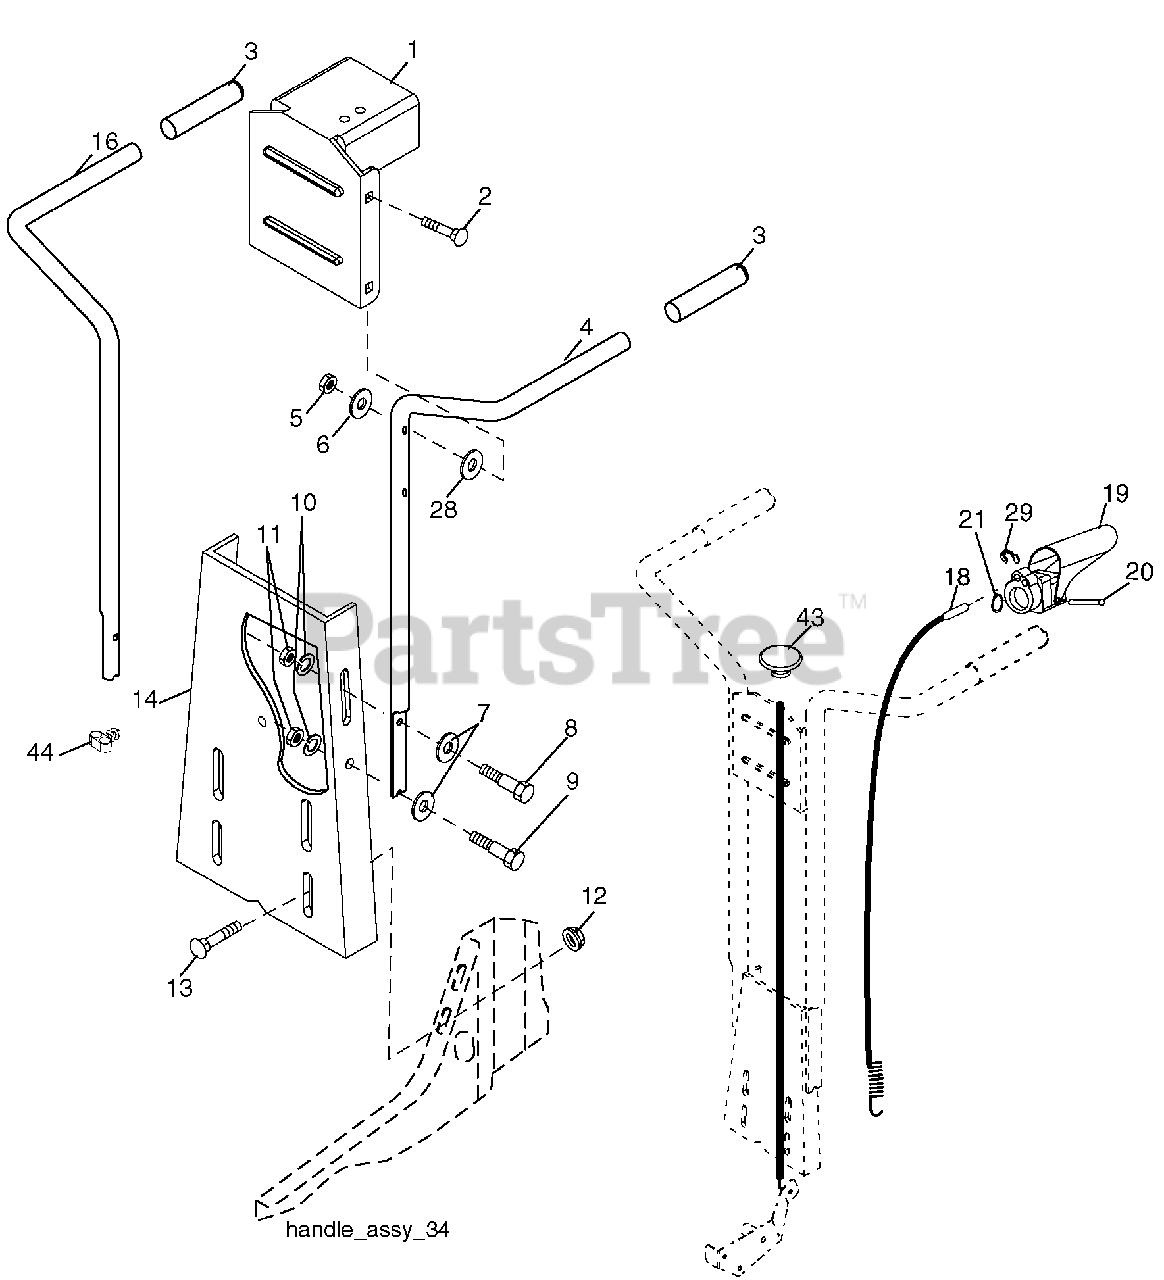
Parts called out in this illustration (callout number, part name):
1	Bracket Handle
2	Bolt, Carriage 5/16-18 unc x 1-1¦2
3	Grip, Handle
4	Handle, L.H.
5	Locknut, Crown 5/16-18
6	Washer 11/32 x 11/16 x 16 Ga.
7	Washer 3/8 x 7/8 x 14 Ga.
8	Bolt, Hex Hd. 5/16-18 x 1
9	Bolt, Hex Hd 5/16-18 x 3/4
10	Washer, Lock 5/16
11	Nut, Hex 5/16-18
12	Nut, Flanged 5/16-18
13	Bolt, Carriage 5/16-18 x 3/4 Gr. 5
14	Panel, Handle
16	Handle, R.H.
18	Cable, Control, Tine
19	Lever, Control, Tine
20	Pin, Pivot
21	Ring, Klip
28	Washer 13/32 x 13/16 x 12 Ga.
29	Retaining, Ring
43	Cable Assembly, Reverse
44	Clip
